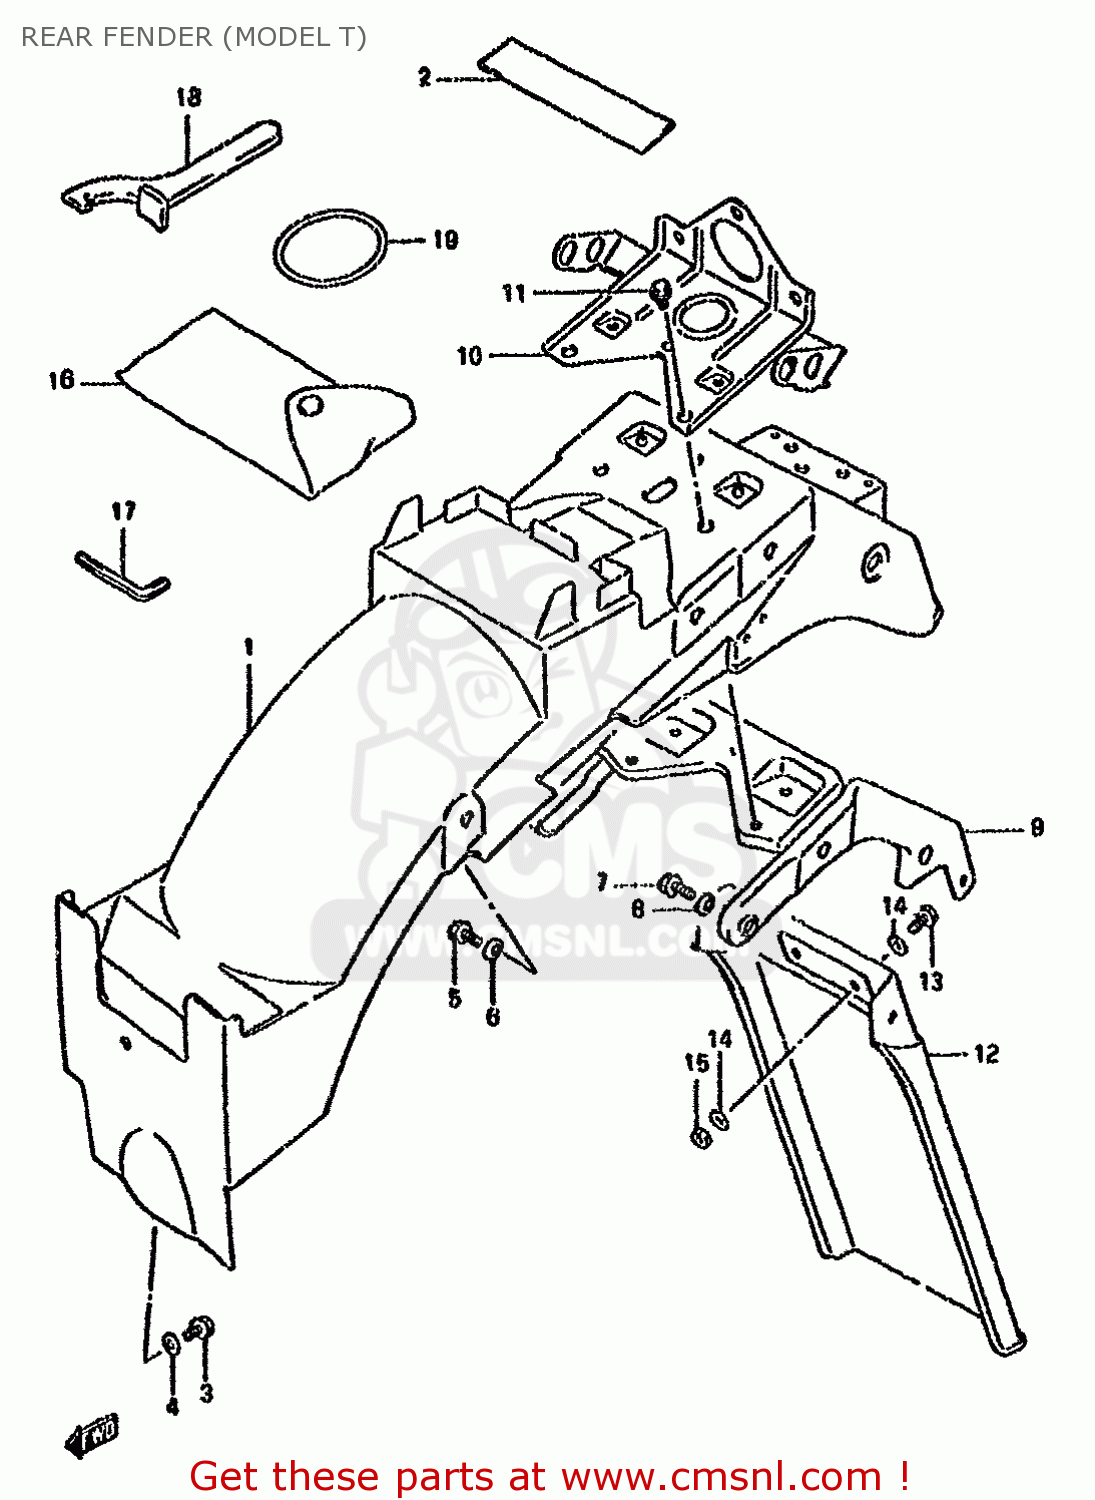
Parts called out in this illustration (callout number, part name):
1	BODY,RR FENDER
2	CUSHION,RR FENDER
3	BOLT
4	WASHER
5	BOLT
6	WASHER
7	BOLT
8	WASHER
9	REINF,RR FENDER
10	BRACKET,RR LAMP
11	BOLT
12	EXTENSION, REAR FENDER
13	SCREW
14	WASHER(6.5X16X1.2)
15	NUT
16	TOOL ASSY
17	SCREW
18	CLAMP
19	NUT
20	MUD GUARD SET
21	SCREW
22	WASHER(6.5X16X1.2)
23	NUT 6MM
24	TOOL ASSY
25	TOOL ASSY
26	CLAMP
27	O-RING
28	MANUAL,OWNER'S
